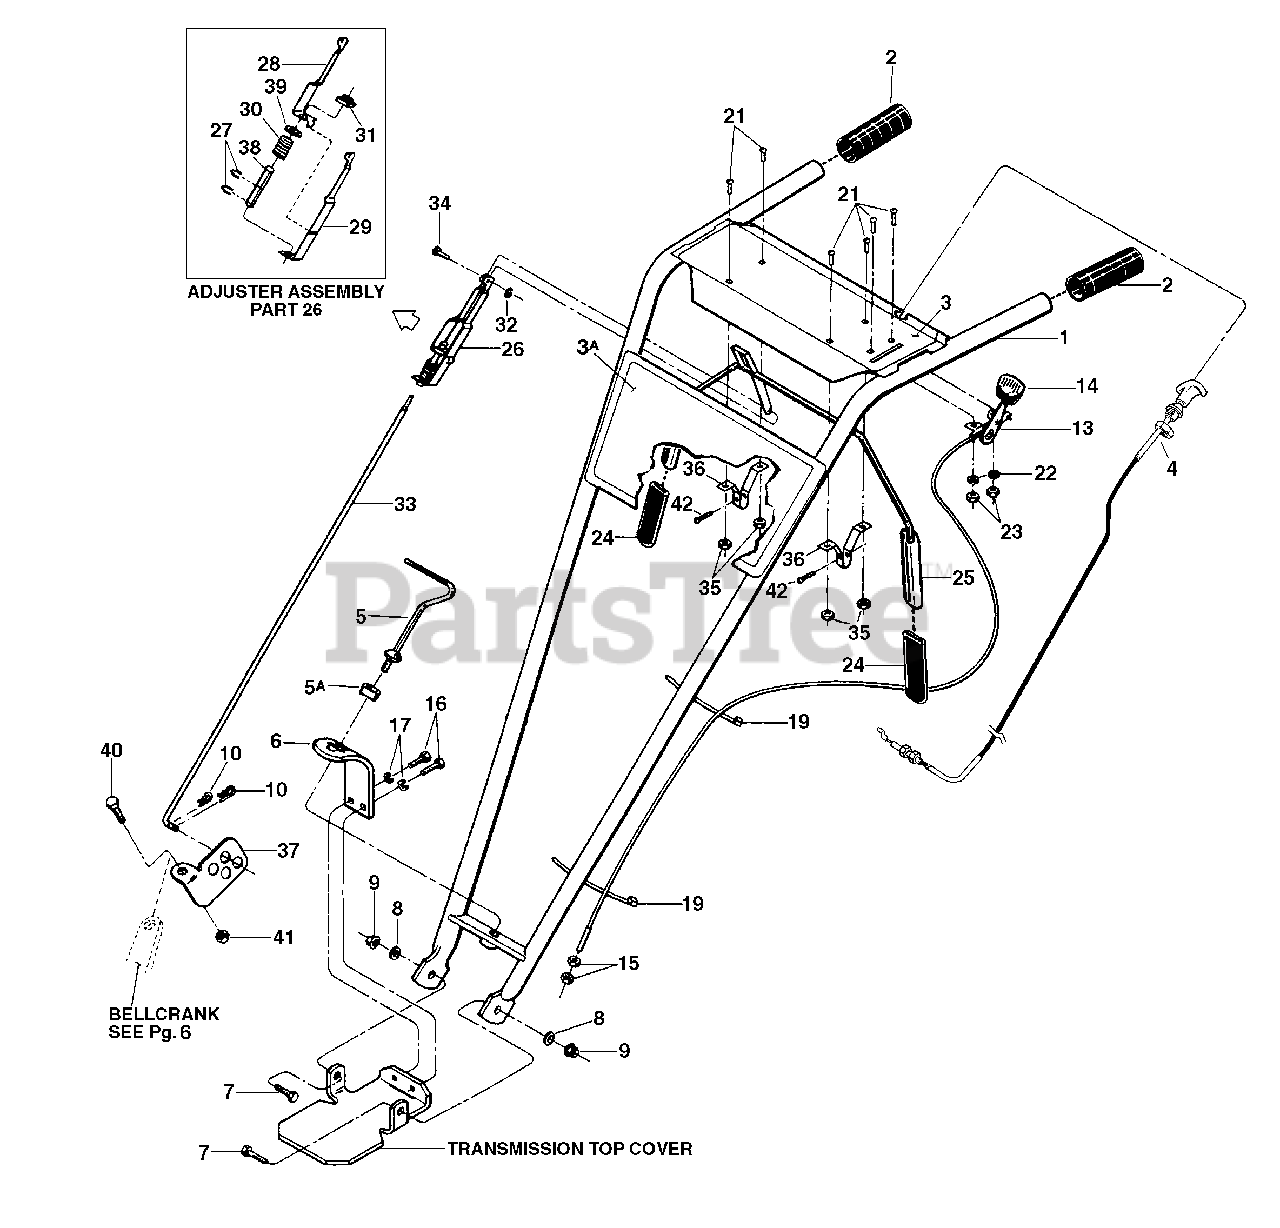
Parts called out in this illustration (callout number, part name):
1	Handlebars-
2	Grip-handlebars
3	Decal-for operator control panel
3A	Decal-Troy-Bilt Pro Line
4	Reverse Cable Assembly
5	Handle, Height Adjustment
5A	Washer-keyed
6	Bracket-handlebar height adjust
7	Screw-hex hd., 3/8-16 x 1
8	Washer-plain (flat) 3/8, S.A.E.
9	Locknut-hex, 3/8-16
10	air Pin Cotter
13	Wheel Gear Control & Cable Assy.
14	Knob-wheel gear control lever
15	Nut-hex, 5/16-24, wheel gear cable adjustment
16	Screw-hex hd., 3/8-16 x 3/4
17	Lockwasher-3/8
19	Ties-plastic
21	Screw-round hd, No. 10-32 x 1/2
22	Lockwasher-No. 10
23	Nut-hex, No. 10-32
24	Grip-paddle
25	Bail-forward clutch control
26	Adjuster Assembly
27	Klip Ring
28	Adjuster, Right Side
29	Adjuster, Left Side
30	Spring-Adjuster
31	Nut-rectangular
32	Klip Ring
33	Rod-forward clutch
34	Pin-Clevis
35	Sems Nut
36	Bracket-bail support
37	Swivel
38	Bushing
39	Washer
40	Screw-hex hd., 1/4-20 x 3/4
41	Nut-1/4-20
42	Screw-flanged hex hd, self-tapping, 1/4-20 x 1/2
